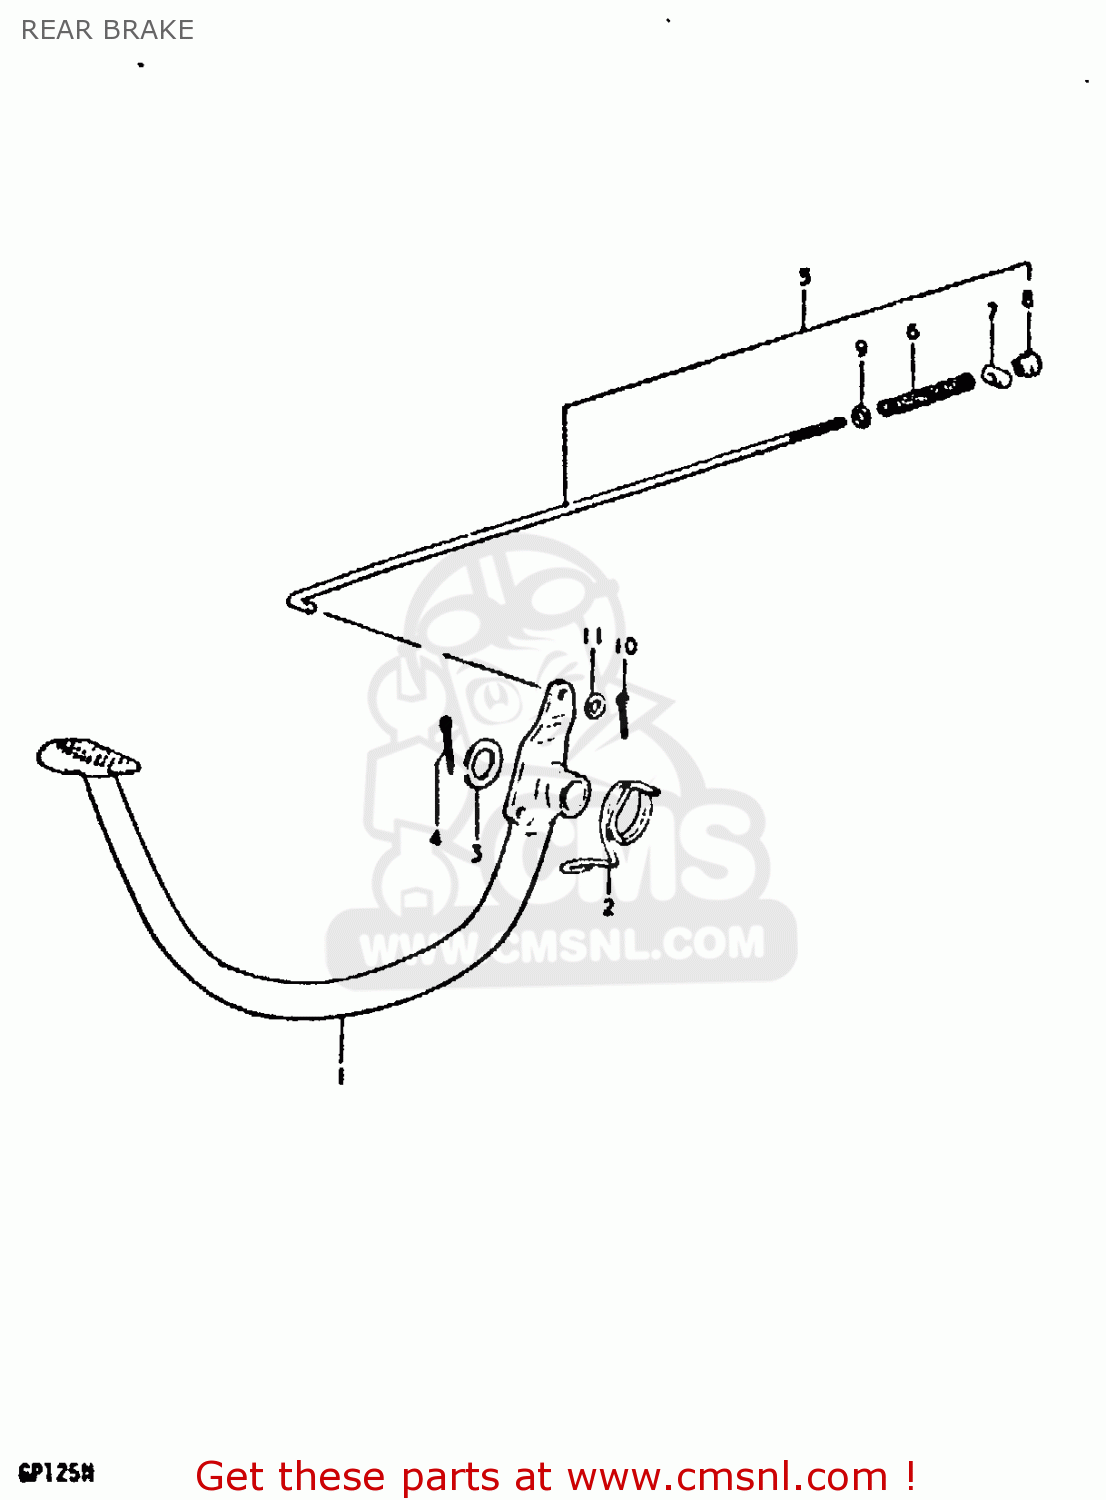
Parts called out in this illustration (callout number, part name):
1	PEDAL,BRAKE
2	SPRING
3	WASHER(15.5X26X2.3)
4	COTTER PIN
5	ROD ASSY, REAR BRAKE
6	SPRING
7	PIN(11X18)
8	NUT
9	WASHER
10	PIN 20X20
11	WASHER
